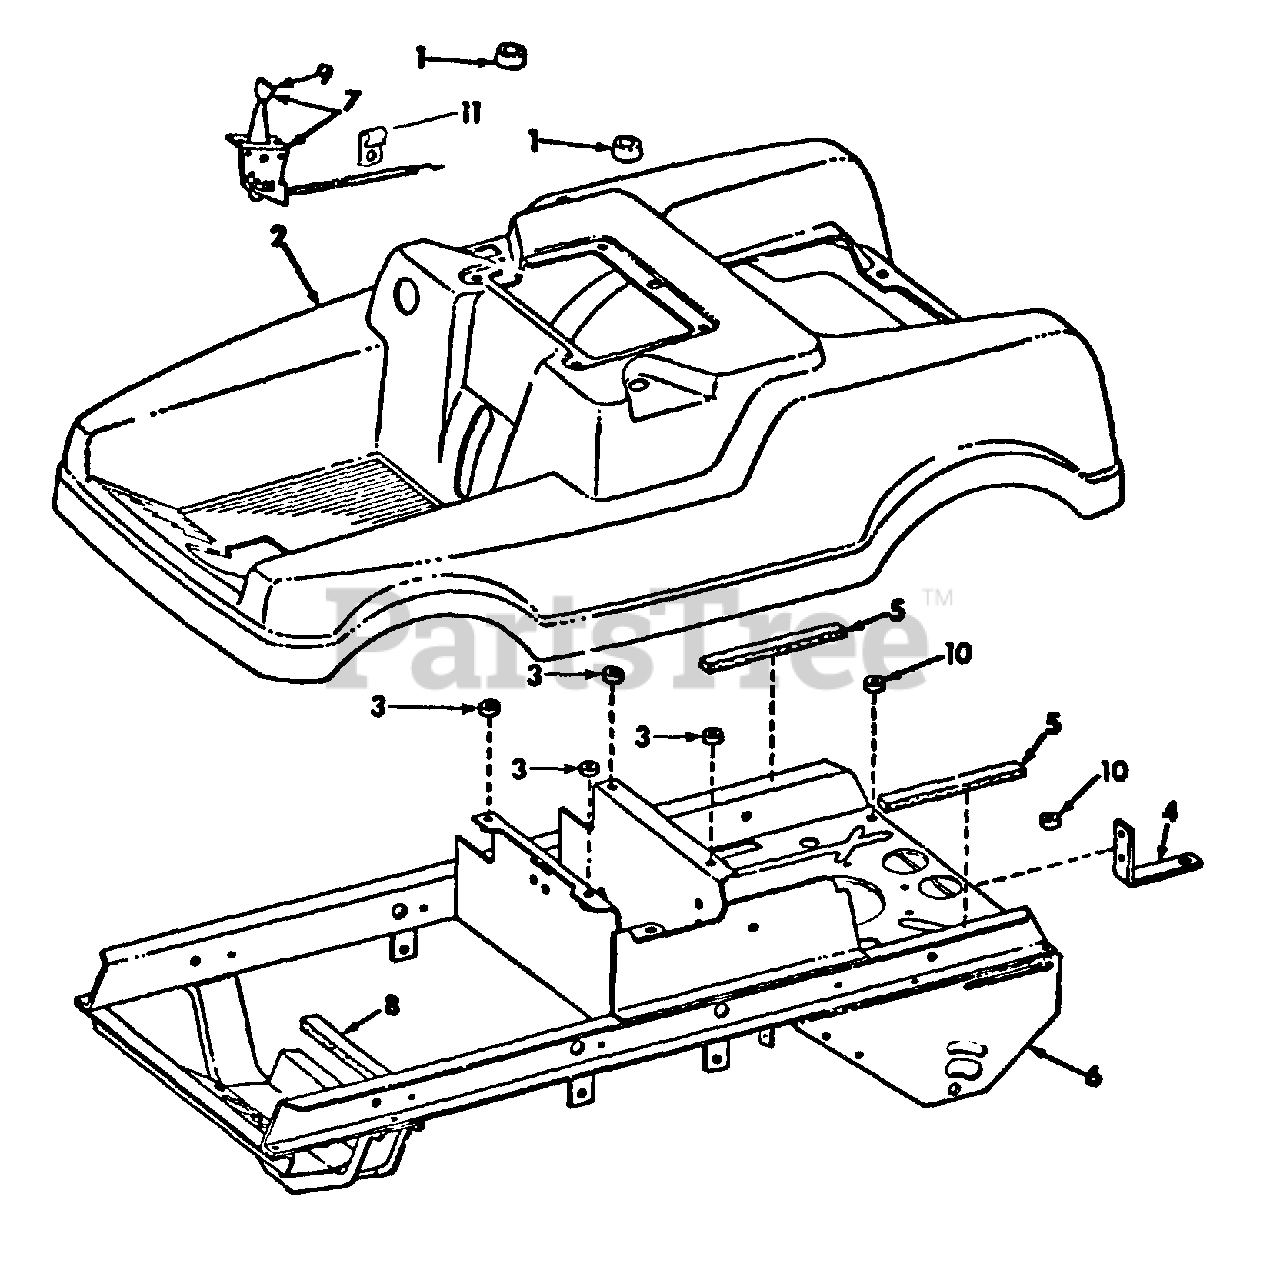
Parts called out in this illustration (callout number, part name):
1	BUMPER, SEAT SUPPORT REAR
2	BODY W/PLUG, 432 485 AND PLUG, 432 580, RIDING MOWER
3	SPACER, BODY MOUNTING
5	STRIP, FOAM GASKET SEALING
6	FRAME W/PRODUCT GRAPHIC, MAIN
7	CONTROL, THROTTLE
8	STRIP, FOAM GASKET SEALING
9	KNOB, THROTTLE CONTROL
10	SPACER BODY MTG REAR
11	NOT USED IN THIS APPLICATION
